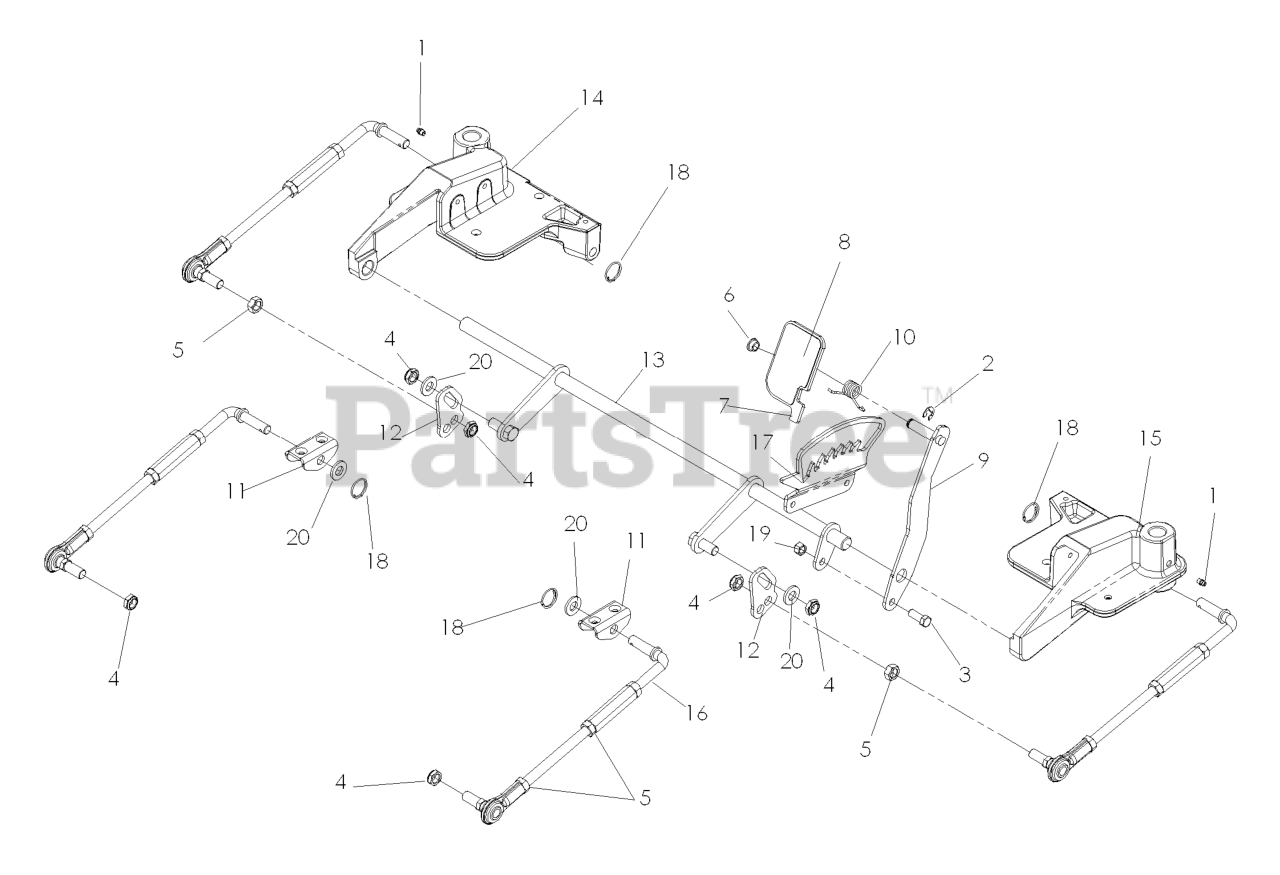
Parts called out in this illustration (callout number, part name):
2	E-RING 1/2 (2 2)
3	HEX BOLT 3/8 X 1"
4	JAM NUT 1/4C (2 2 PW01)
5	NUT 1/2-20 HEX JAM ZD
6	BUSHING, FLANGED NYLON
7	FOOT PEDAL
8	FOOT PAD, NON-SLIP
9	LIFT FOOT, LEVER WELDED
10	SPRING, PEDAL, LIFT
11	BRACKET, DECK HANGER
12	CONNECTOR, DECK LIFT
13	LIFT SHAFT WLDT
14	CASTING, CASTER, LT
15	CASTING, CASTER, RT
16	LINKAGE ASM, LIFT
17	HEIGHT PLATE, DECK
19	NUT 3/8-16 NYLOC
20	WASHER 1/2" FLAT
